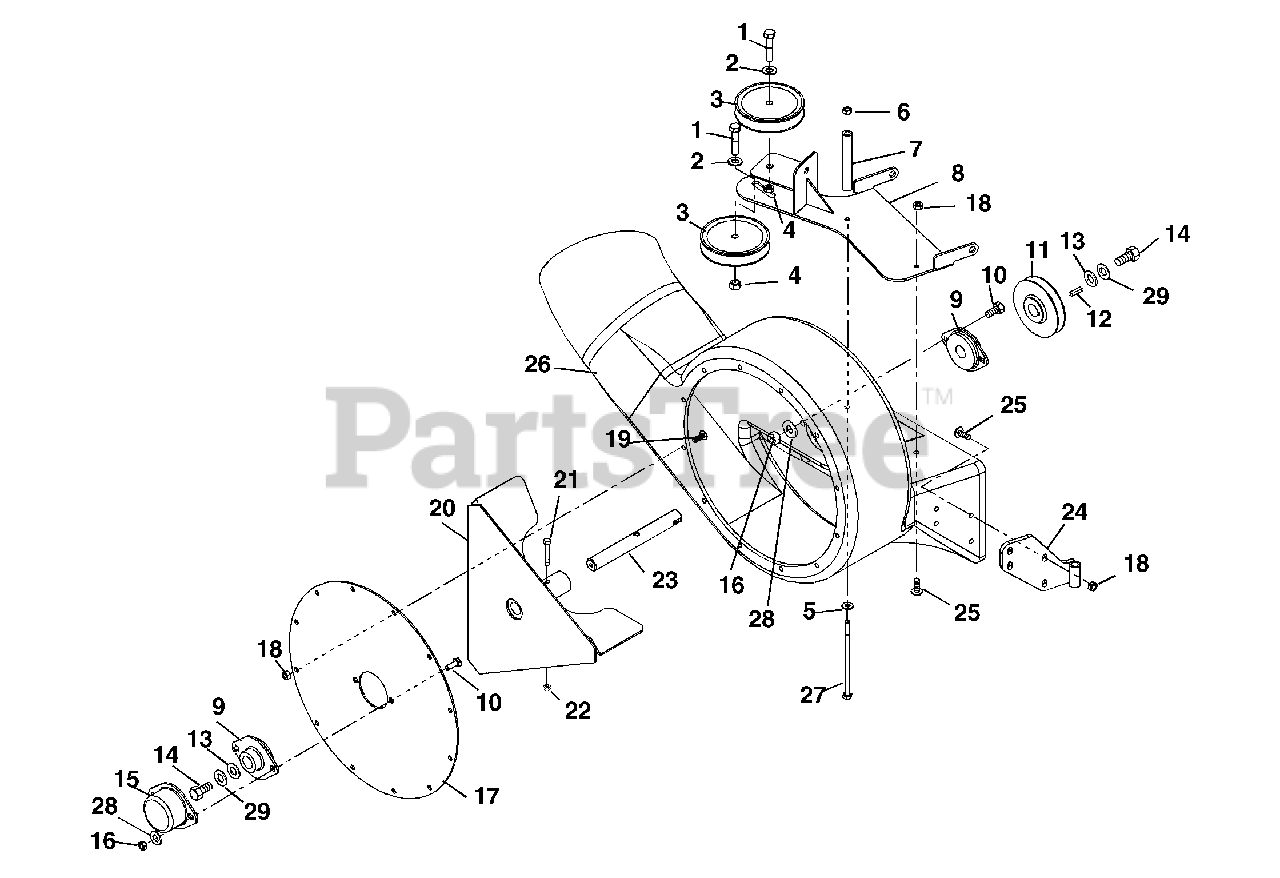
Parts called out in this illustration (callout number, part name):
1	@BLT-HEX .38-16X1.50 GR5 YWZC
2	@WSHR-FL-STL.38X.875X.083 YWZC
3	IDLER-V 4.00 X .38 NWHAMSHR
4	@NUT-SPNLK-FLG .375-16 YWZC
5	@WSHR-FL-STL.281X.62X.065 YWZC
6	@NUT-LK-CTR .25-20 YWZC
7	SPACER .334X.500X4.625
8	BRACKET COMP-MULE PULLEY
9	BEARING, 2 BOLT FLANGE -.75 ID
10	@BLT-HEX .31-18X1.00 GR5 YWZC
11	PULLEY, DRIVEN 3.50
12	KEY-SQ .187 X .50 X .187
13	WSHR-FL-STL .328X1.0X.094 YWZC
14	BLT-HEX .25-28X.75 GR5 YWZC
15	COVER-BEARING
16	@NUT-LK-NYL .312-18 YWZC
17	PLATE-BEARING MOUNTING
18	@NUT-SPNLK-FLG .25-20 YWZC
19	SCR-MCH .25-20X.50 TXTR PL
20	IMPELLER, GRASS PUMP
21	@BLT-HEX .25-20X1.50 GR5 YWZC
22	@NUT-LK-CTR .25-20 YWZC
23	SHAFT, GRASS PUMP - .75 OD
24	MOUNTING BRACKET COMPLETE
25	SCR-MCH .25-20X.75 TXTR YWZC
26	HOUSING, BLOWER
27	@BLT-HEX .25-20X6.00 GR5 YWZC
28	@WSHR-FL-STL.312X.734X.065 YWZ
29	@WSHR-LK .25X.062 REG YWZC
